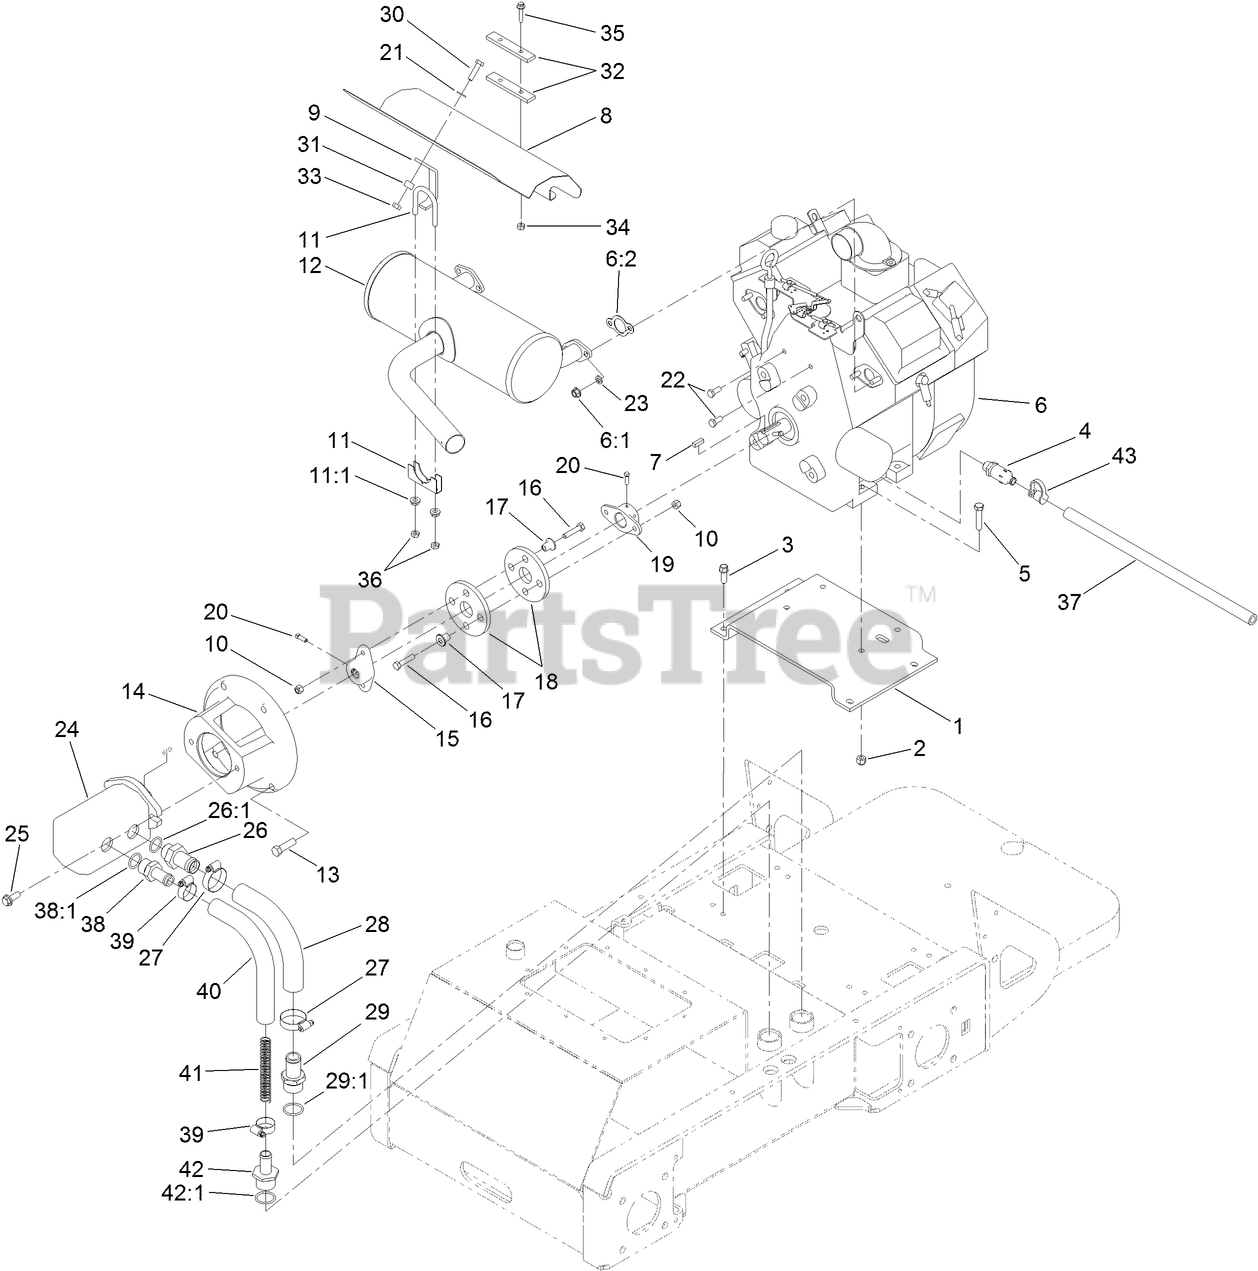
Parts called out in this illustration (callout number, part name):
1	MOUNT-ENGINE
2	NUT-LOCK, NI
3	SCREW-TAPTITE
4	VALVE-DRAIN, OIL
5	SCREW-HH
6	ENGINE-KOHLER, CH680S
6:1	NUT-HF
6:2	GASKET-EXHAUST
7	KEY-SQUARE
8	SHIELD-MUFFLER
9	SUPPORT-SHIELD
10	NUT-LOCK, NI
11	CLAMP
11:1	NUT-HF
12	Muffler
13	SCREW-HH
14	MOUNT-PUMP
15	HUB-PUMP
16	SCREW-HH
17	SPACER
18	COUPLING-RUBBER
19	HUB-ENGINE
20	SCREW-SQH
21	WASHER-PLAIN
22	SCREW-HH
23	WASHER-LOCK
24	HYD PUMP ASM
25	SCREW-HHF
26	FITTING
26:1	O-RING
28	HOSE-SUCTION, FORMED
29	FITTING-STR
29:1	O-RING
30	SCREW-HH
31	SPACER
32	SPACER-BAR
33	NUT-LOCK, CONE
34	NUT-LOCK, CONE
35	SCREW-HHF
36	NUT-JAM
38	FITTING-STRAIGHT
38:1	O-RING
39	CLAMP-HOSE
40	HOSE-SUCTION, HYD
41	Spring-Compression
42	FITTING-HOSE, BARBED
42:1	O-RING
43	CAP-DUST
